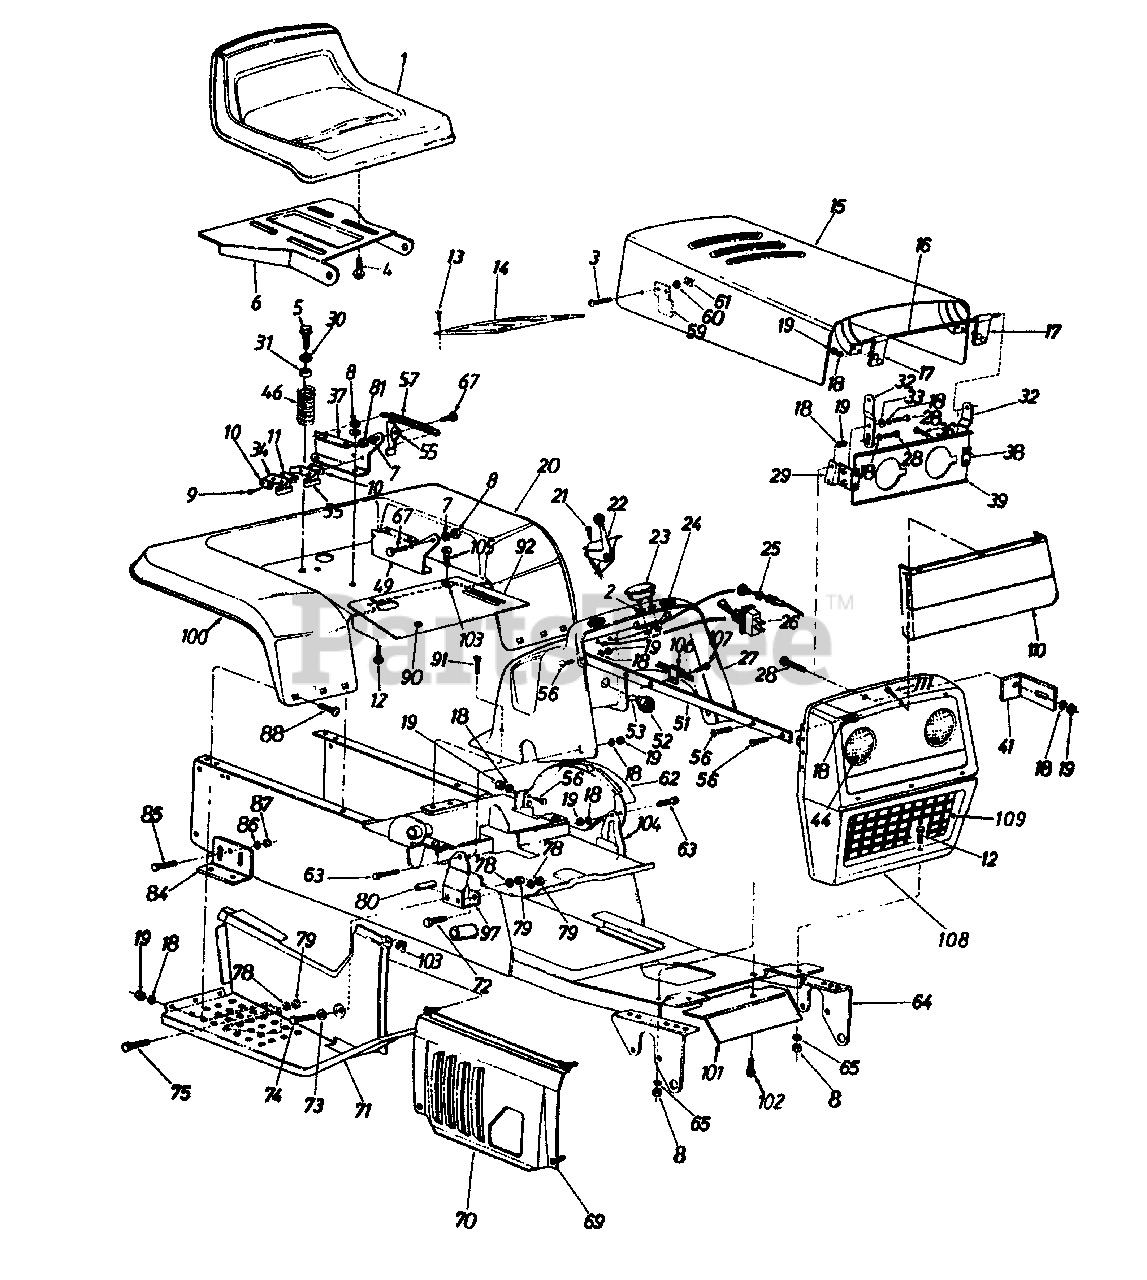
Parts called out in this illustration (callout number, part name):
1	Seat Assembly (Yellow)
2	Lock Washer 190" I.D.
3	Truss Hd. Mach. Scr. #10-24 x .38"
4	Hex Wash. Hd. Self-Tap Scr. 3/8-16 x .75" 5
7	L-Wash. 5/16" I.D.
8	Hex Nut 5/16-18 Thd. Grade 5
9	Hex Wash, Hd. AB-Tap Scr. #8 x .5"
10	Insulator Plate
11	Insulator Boss Plate
12	Hex Bolt 5/16-18 x .75" Lg.
13	Self-Tap Oval Hd. Scr. 1/2" Lg.
14	Dash Panel Cover
17	Hood Hinge Assembly
18	L-Wash. 1/4" I.D.
19	Hex Nut 1/4-20 Thd.
22	Throttle Control
23	Ammeter
24	Rubber Bumper
25	Choke Control
26	Light Switch
27	Dash Panel
28	Hex Bolt 1/4-20 x .62" Lg.
29	Hood Support Brkt. Assembly.-R.H.
30	Fl-Wash, .344" I.D. x .875"
31	Bushing
34	Safety Switch (Seat)
35	Safety Switch (Seat)
36	Hex Bolt 1/4-20 x .38" Lg.
38	Hood Support Brkt. Assembly-L.H.
41	Heat Shield Brkt.
44	Head Lamp
46	Compression Spring 4.5" Lg.
53	Ignition Key
55	Seat Lift Bracket
56	Hex Bolt 1/4-20 x .75" Lg.
57	Extension Spring 5.31" Lg.
59	Hood Spring
60	L-Wash. #10
61	Hex Nut #10-24 Thd.
67	Shld. Bolt .437" Dia. x .268"
69	Truss Mach. Scr. #10-24 x .5" Lg.
73	Fl-Wash. .385" I.D. x .62" O.D.
74	Hex Bolt 3/8-16 x 3.00" Lg.
75	Hex Bolt 3/8-16 x 1.00" Lg. Grade 5
78	L-Wash. 3/8" I.D.
79	Hex Nut 3/8-16 Thd.
80	Spacer .375" I.D. x .62" O.D. x 2"
81	Hex Nut 5/16-18 Thd. (Gr. 5)
84	Transaxle Support Brkt.
85	Rd. Hd. Rib Neck Scr. 3/8-24
86	L-Wash. 3/8" I.D.
87	Hex Nut 3/8-24 Thd. (Gr. 5)
88	Carr. Bolt 1/4-20 x .50" Lg.
90	Snap Bushing
91	Hex Wash. Hd. Tap Scr. 1/4-20 x .5"
103	Speed Nut #10-24 Thd.
104	Dash Panel Mtg. Brkt.-L.H.
105	Truss Mach. Scr. #10-24 x .5"
106	Clamp
107	Self-Tap Scr. 5/16 x .5" Lg.
110	Headlight Bezel
111	Hex Washer Head Screw #8 x .5"
